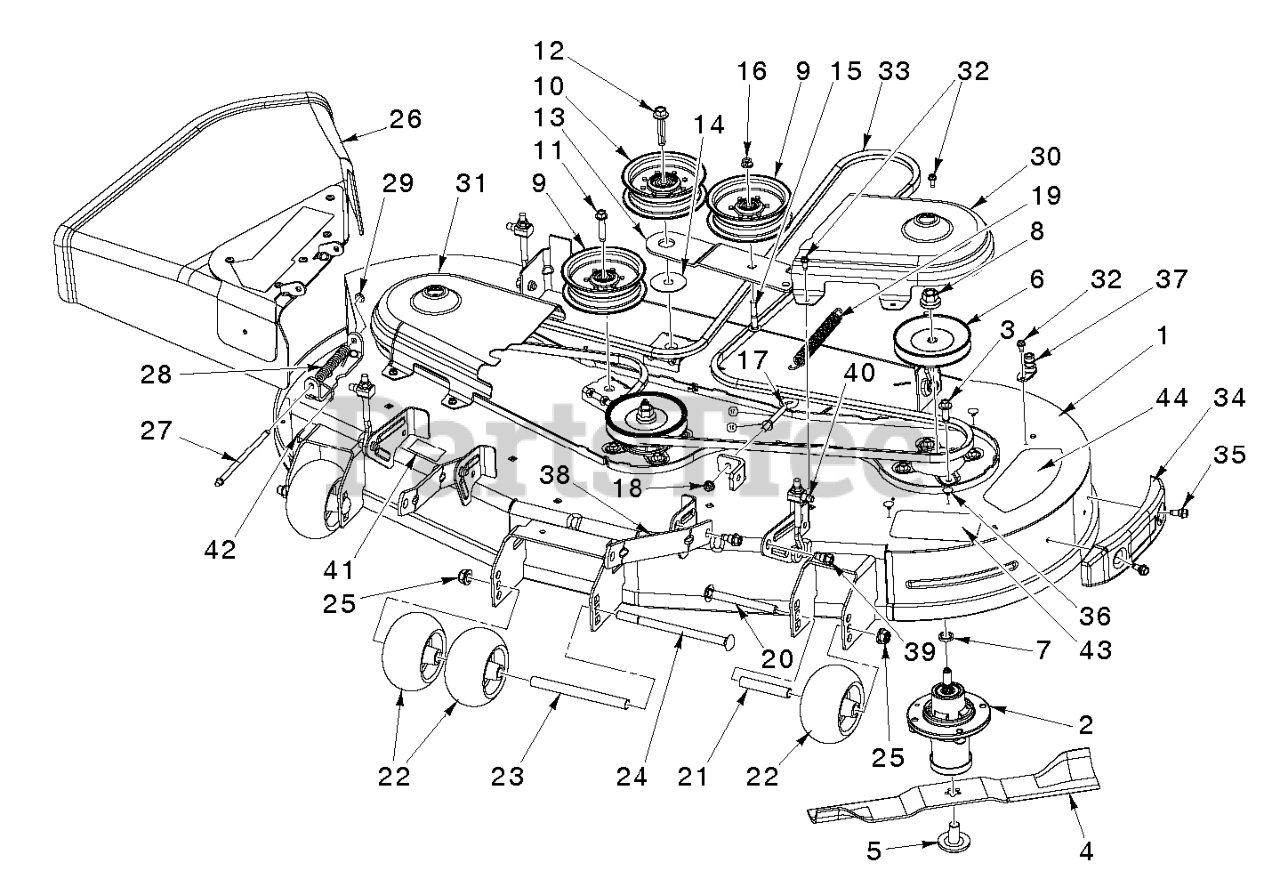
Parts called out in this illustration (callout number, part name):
1	DECK.SVC.54.CLRCT.MZ.MS668
3	BOLT.HEX.WASHR.HED.313-18X1.19
4	BLADE.54CC.HI-LIFT.PZ.197".431
5	BLADE BOLT/WASHER
7	WASHER.SPACER.MANDREL
9	PULLEY.IDLER.2006
10	PULLEY.IDLER.MWR.STATI.LH
11	BOLT;HEX_3/8-16 X 1.78.CLRZINC
12	SCREW.7/16-14 X 2.125.WASHER
13	ARM IDLER ARM, CLEARCUT 54 BLA
16	NUT LOCK FLG 3/8-16 UNC
17	GSPW Bolts
18	GSPW Hardware
19	SPRING.MOWER.DRIVE.ELECTRIC
22	ROLLER, GAUGE .635 BORN
25	NUT 1/2-13 HEX FLANGE NYLOK CL
26	DEFLECTOR ASSY 54 CLEARCUT RES
27	ROD.HINGE
28	SPRING.42.FCS.DEFLECTOR
29	NUT PUSH M
30	COVER.PNT.54CC.MNDRL.LH.ZTR.GY
31	COVER 54 CLEARCUT RH MANDREL G
32	SCREW.1/4-20X5/8
33	BELT CLEARCUT 54, MZ DECK DRIV
34	BUMPER ASSY 54 CLEARCUT TRIM S
35	SHOULDER BOLT 5/16-18TT
36	PLUG CHRISTMAS TREE
37	PORT.WASHOUT
38	ARM.RFIXED.MOWER.SUSPNSIONX431
39	BOLT.SHOULDER
40	LINK.ASM.ADJUSTABLE
40	NUT.HEX.FLANGE.INS.BLK.3/8-16
41	DECAL BELT ROUTING DECAL DECAL
42	CAP-SLEEVE LT
44	DECAL DECK DECAL DECAL.54DECK.
